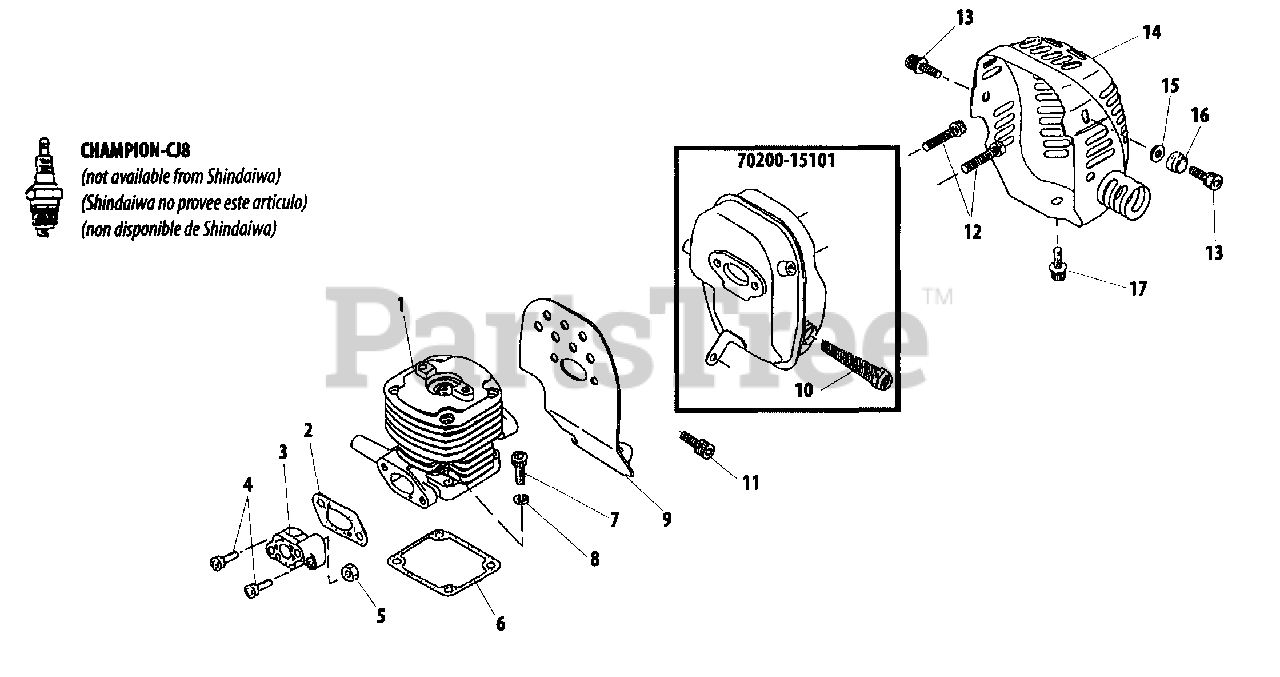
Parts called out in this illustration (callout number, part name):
1	CYLINDER
2	GASKET, INTAKE
3	INSULATOR, INTAKE
4	BOLT M5×25
5	NUT M5×6.3
6	GASKET, CYLINDER
7	BOLT 5×25
8	WASHER, SPRING 5
9	GASKET, EXHAUST
10	SCREEN, SPARK ARRESTER
11	BOLT M5×12
12	BOLT 6×25
13	BOLT M5×10
14	COVER, MUFFLER
15	WASHER
16	COVER
17	BOLT M5×10
70200-15101	MUFFLER ASSY
